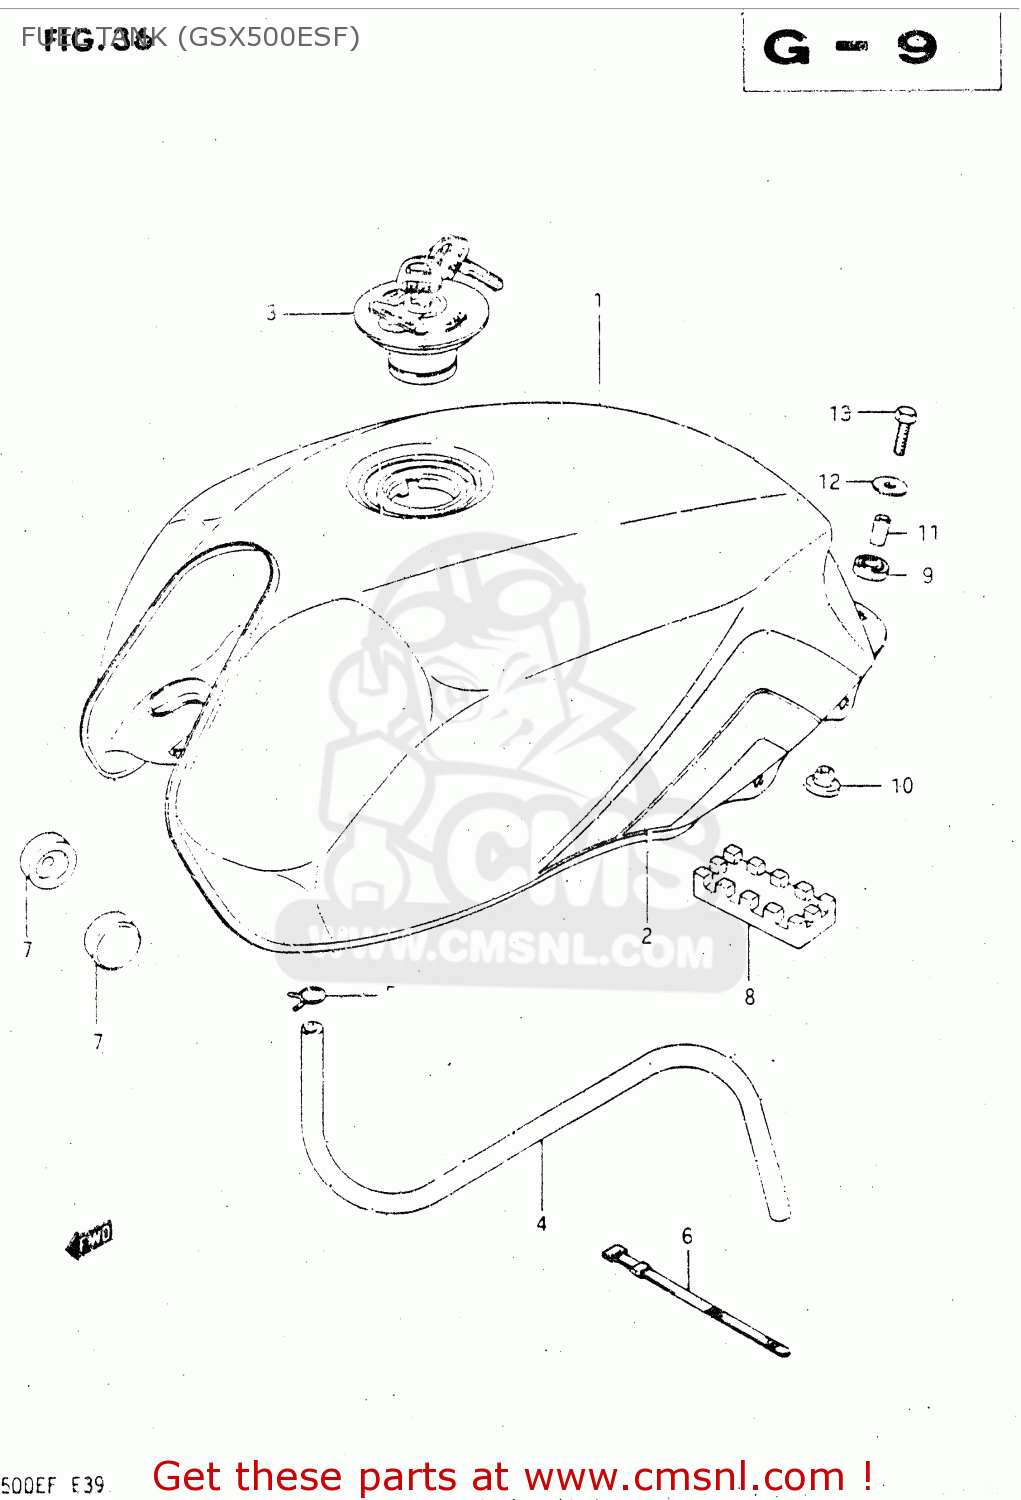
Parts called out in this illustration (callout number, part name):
1	TANK ASSY, FUEL
2	TAPE SET,FUEL TANK
3	CAP ASSY,FUEL TANK
4	HOSE,FUEL
5	CLIP
6	CLAMP(L:187)
7	CUSHION
8	CUSHION,FUEL TANK
9	CUSHION
10	CUSHION
11	SPACER (6.4X9X20)
12	WASHER (6.5X24X1.6)
13	BOLT
